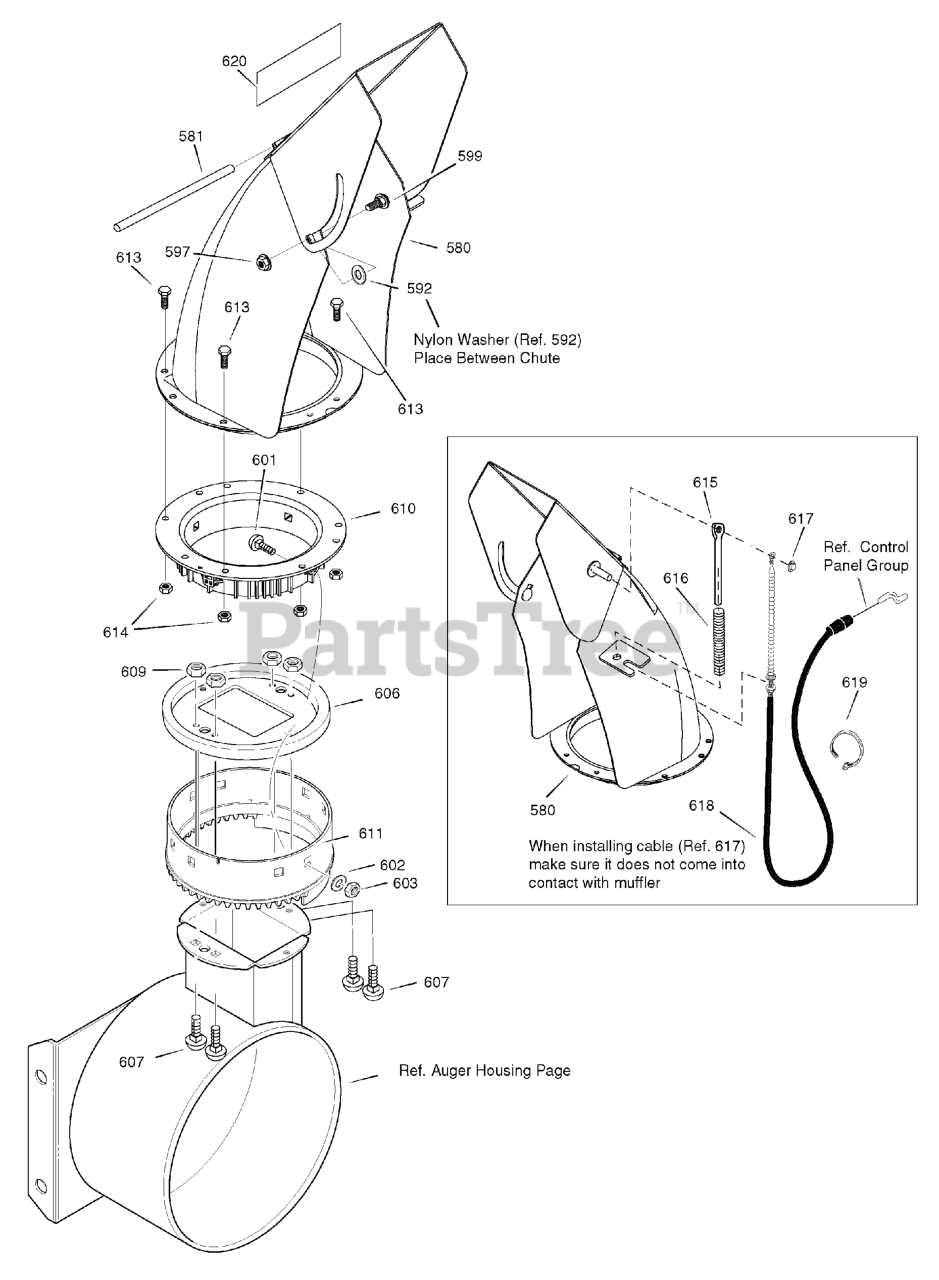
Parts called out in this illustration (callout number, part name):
580	CHUTE ASSEMBLY
581	PIN, HINGE
592	WASHER, Nylon
597	NUT, Hex-Flange, 5/16-18
599	BOLT, Carriage, Short Neck, 5/16-18 x 1
601	BOLT, 5/16-18 X 1.00
602	WASHER, Flat
603	NUT, Hex, Nylock, 5/16-18
606	CHUTE COLLAR
607	SCREW, 1/4-20 X 0.75
609	NUT, Nylock Flanged, 1/4-20
610	RING, Retainer, Inner
611	RING, Retainer, Outer
613	CAPSCREW, Hex-Flange, 1/4-20 x .75
614	NUT, Nylock Flanged, 1/4-20
615	ROD, Spring
616	SPRING, Compression
617	NUT, Push-Cap, 5/16
618	LEVER & CABLE, CHUTE DEFLECTOR
619	TIE, Cable
620	DECAL, Hinge
